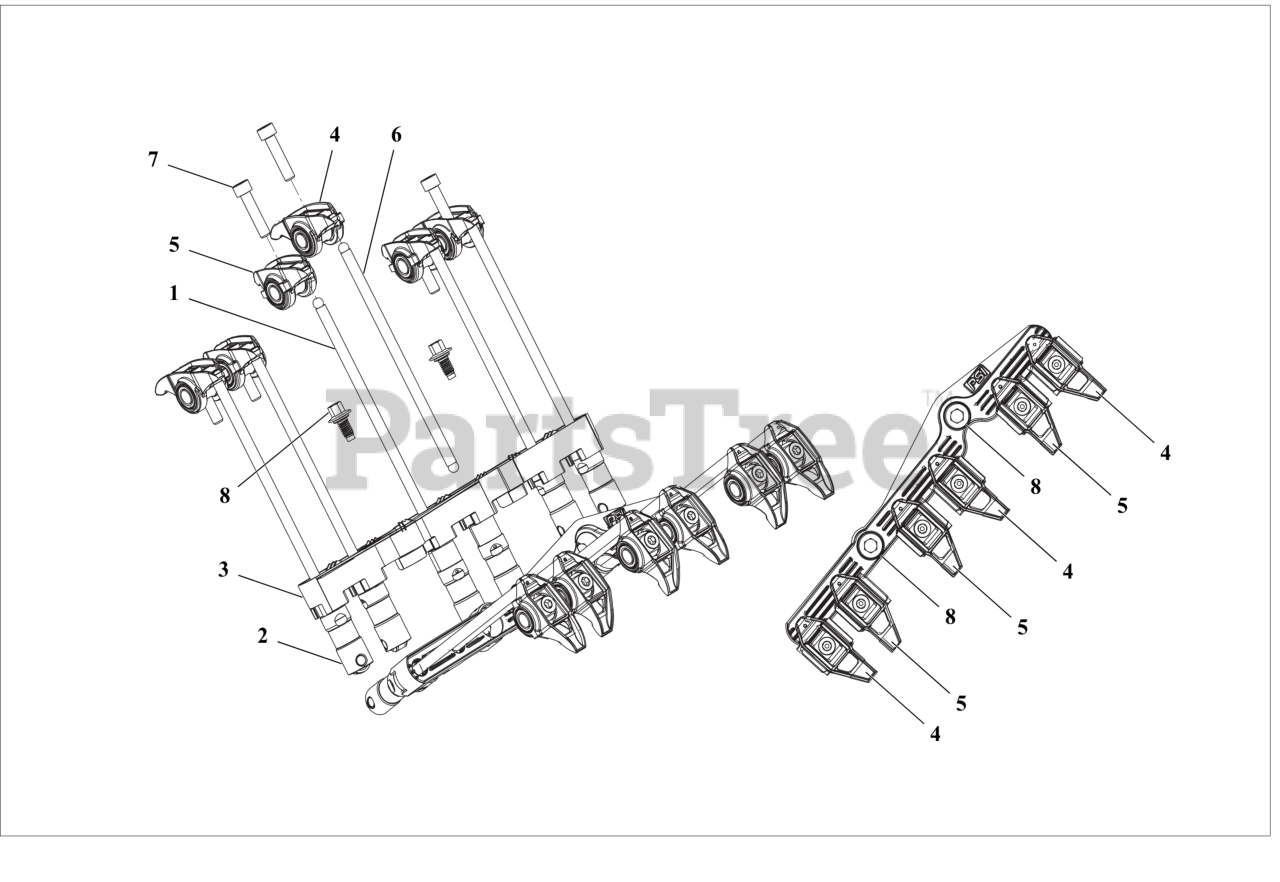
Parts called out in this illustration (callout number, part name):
1	*PUSH ROD (INTAKE)
2	*LIFTER
3	*LIFTER, BUCKET
4	*ROCKER ARM ASSEMBLY
5	*ROCKER ARM
6	*PUSH ROD (EXHAUST)
7	*BOLT, ROCKER ARM
8	*BOLT, LIFTER BUCKET
